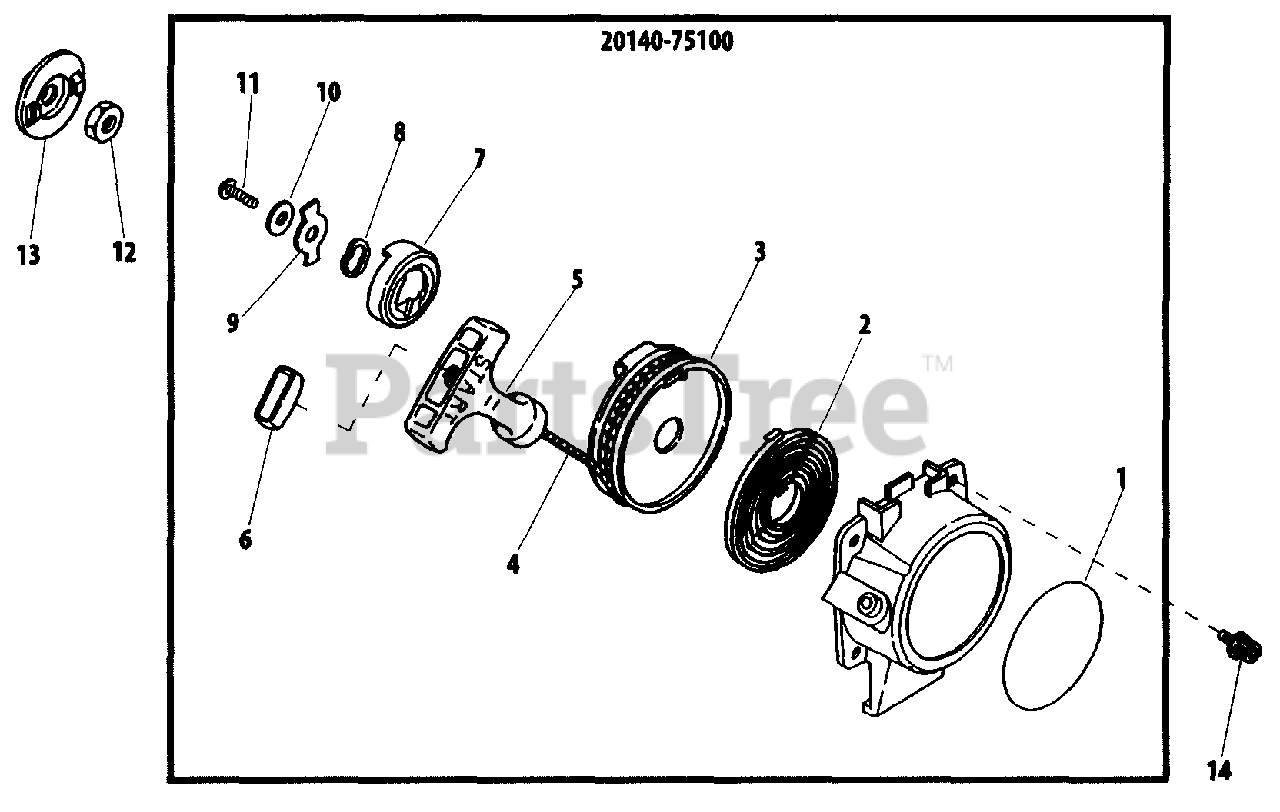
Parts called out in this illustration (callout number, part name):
1	NAMEPLATE
2	SPRING, RECOIL
3	REEL, ROPE
4	ROPE, STARTER
5	GRIP, STARTER
6	RETAINER, ROPE
7	PAWL CATCHER
8	SPRING, COMPRESSION
9	RETAINER
10	WASHER
12	NUT M8×1
13	PULLEY, STARTER
14	BOLT M4×12
20140-75100	STARTER ASSY
